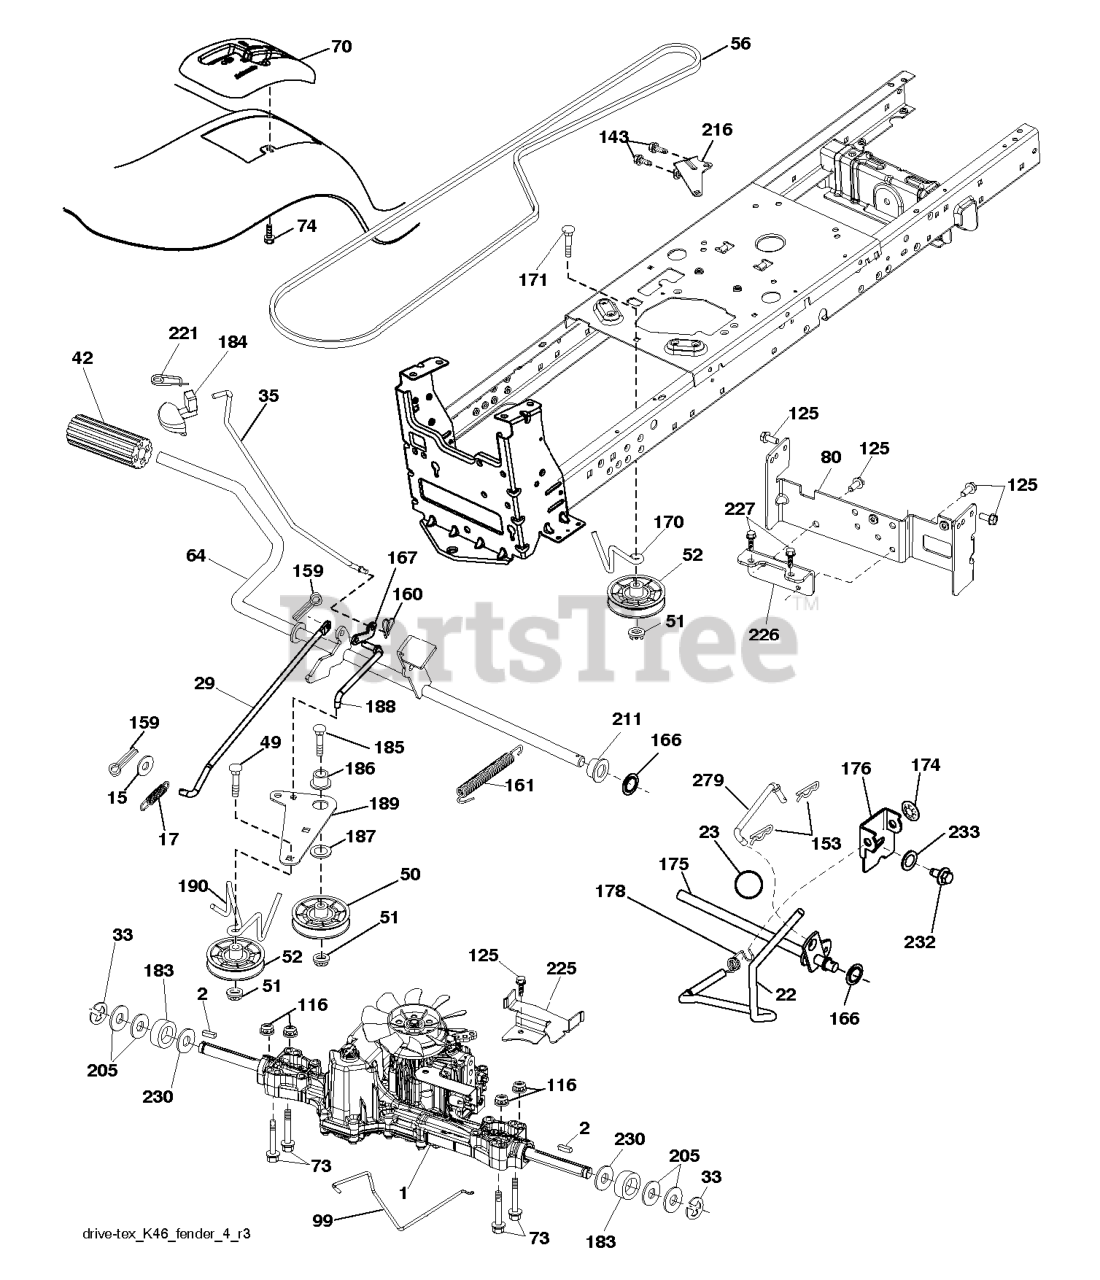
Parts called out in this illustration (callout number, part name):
2	SQUARE KEY
15	WASHER
17	SPRING.BRAKE.K46.GREEN
22	ROD.SHIFT.FENDER.TLT.2006
23	KNOB.DELUXE.(PISTOL.GRIP).BLAC
29	ROD.BRAKE.K46
35	ROD .BRAKE. PARKING. GT. HUSQ.
42	PEDAL COVER T
50	IDLER.FLAT.910.OFFSET
51	NUT LOCK FLG 3/8-16 UNC
52	IDLER.V-GROOVE.910.OFFSET
56	V-BELT.MOWER.92.40.42/K46
64	SHAFT.ASM.PEDAL.BRAKE.
70	CONSOLE SHIFT
74	SCREW.HI-LO.CONSOLE
80	STRAP TORQUE
99	ROD.SPRING.BYPASS.K46.LT.Z
116	NUT LOCK HEX FLANGE 5/16-18
125	SCREW
143	Screw 5/16-18 x 1/2 Hex, Self Tapping 5/16-18 x 1/2
153	RETAINER M
159	COTTER PIN
160	RETAINER CLIP
161	SPRING, RETURN LT
166	NUT.PUSH.625
167	LATCH.BRAKE.SPRING
170	KEEPER.V-IDLER.CENTER.
174	NUT.PUSH.500.2006
175	SHAFT ASM SHIFT
176	ARM.CLEVIS.ROD.SHIFT
178	SPRING.SHIFT.GT2006
183	SPACER AXLE
184	HANDLE.PARKG.BRK.HUSQ X667
186	SPACER.RETAINER
187	WASHER 12/32X2X10GA
188	RP.LINK.CLUTCH.GROUND.DRIVE
189	BELLCRANK.GROUND.DRIVE.TEX.
190	KEEPER.BELLCRANK.DRIVE
211	BUSHING.SHAFT.BRAKE.HAND
216	BRACKET.PULLEY.IDLER.W/TEX
221	RETAINER.SPRING.CLIP.H
225	KEEPER.BELT.TRANSAXLE.K46
226	BRACKET.MOUNT.TORQUE.K46.TLT
227	SCREW.THDROL.5/16-18X3/4.TTY
230	WASHER.HARDENED
232	BOLT FIN HEX 7/16-14 X 1
233	WASHER SERRATED
279	LINK.SHIFT.T/A.K46.FEND.TX
